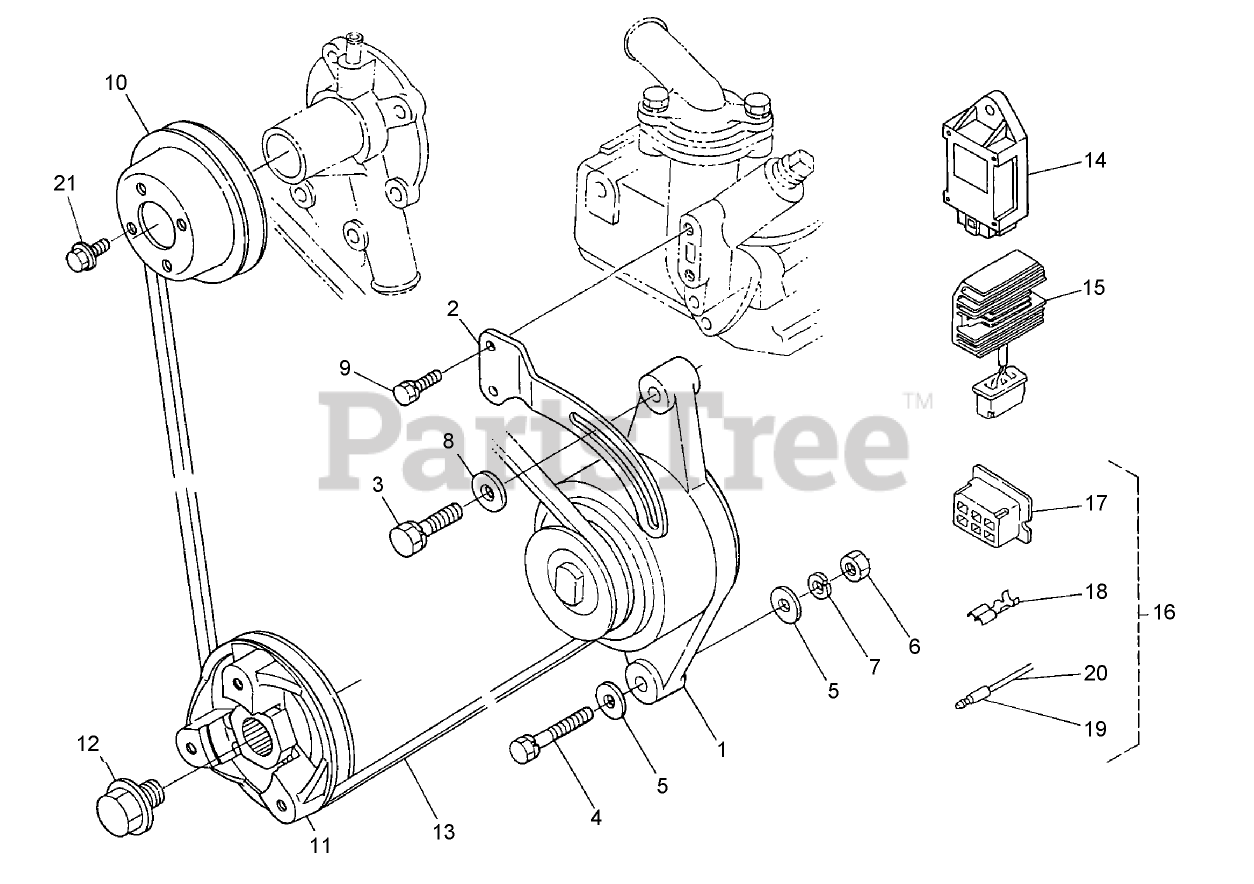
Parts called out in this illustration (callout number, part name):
1	DYNAMO ASM
2	STAY-DYNAMO
5	WASHER-PLAIN
7	WASHER-SPRING
8	WASHER-PLAIN
10	PULLEY-FAN
11	PULLEY-DRIVE, FAN
13	V-BELT
14	CONTROLLER-GLOW
15	REGULATOR ASM
16	COUPLER ASM
17	CONNECTOR
18	TERMINAL
19	TERMINAL
20	SLEEVE
21	BOLT-FLANGE
